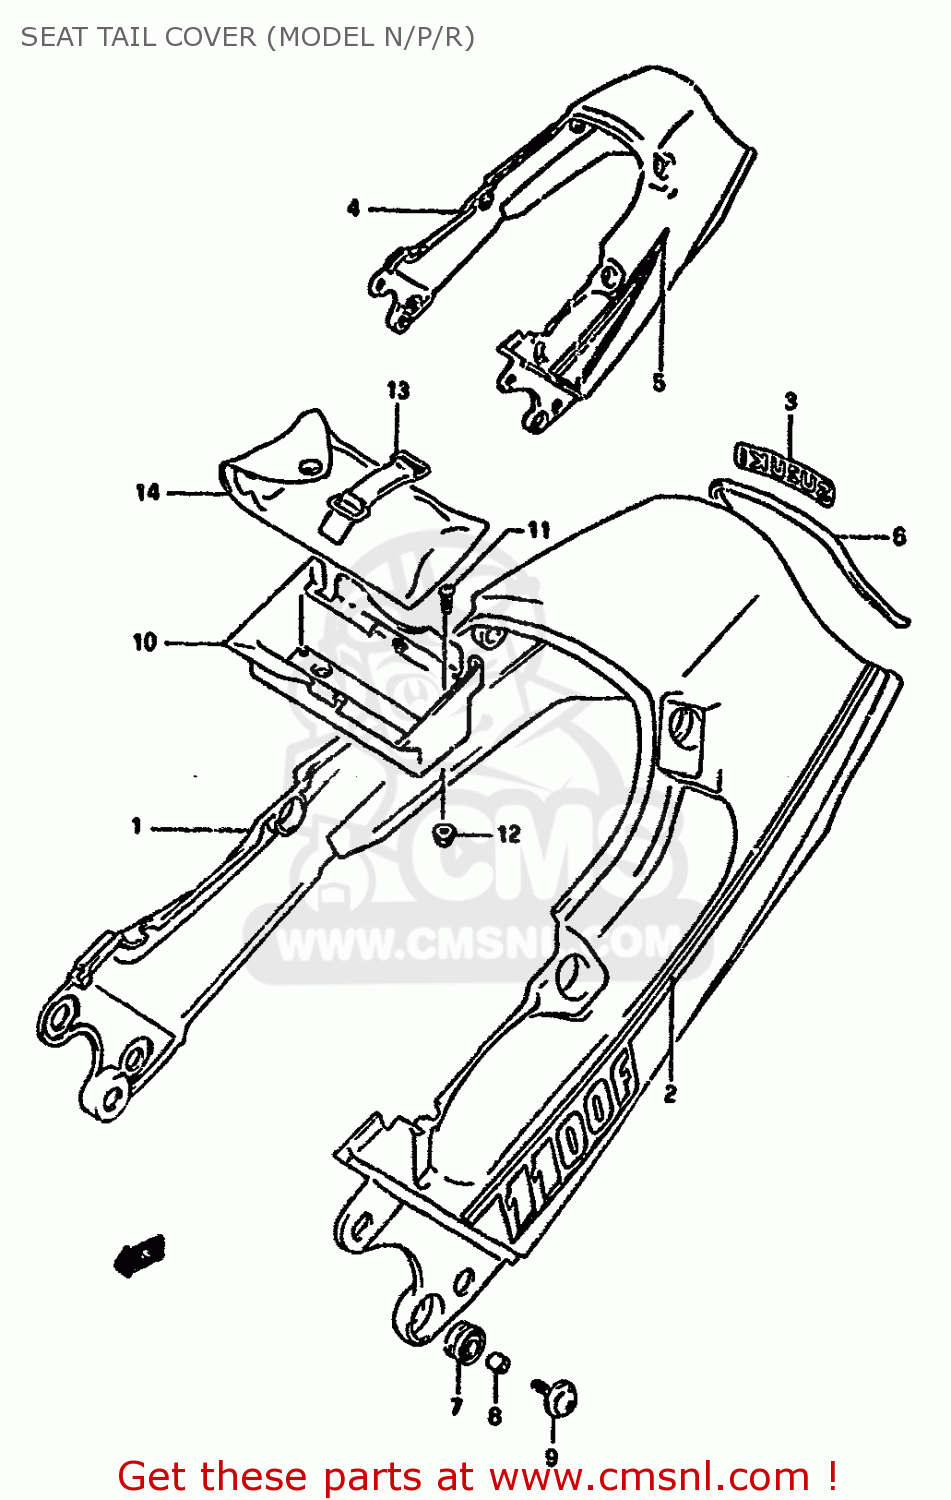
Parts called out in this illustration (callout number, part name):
1	COVER SET,SEAT TAIL
2	TAPE SET,SEAT TAIL COVER
3	EMBLEM
4	COVER SET,SEAT TAIL (RED)
5	TAPE SET,SEAT RAIL COVER
6	MOLDING,SEAT TAIL COVER
7	CUSHION,SEAT TAIL COVER SIDE
8	SPACER (6.1X8X8)
9	SCREW(6X20)
10	HOLDER,TOOL
11	SCREW
12	NUT
13	BAND
14	TOOL ASSY
15	BAND
16	TOOL ASSY
18	HOLDER,TOOL
19	SCREW
20	NUT
21	BAND
22	TOOL ASSY
